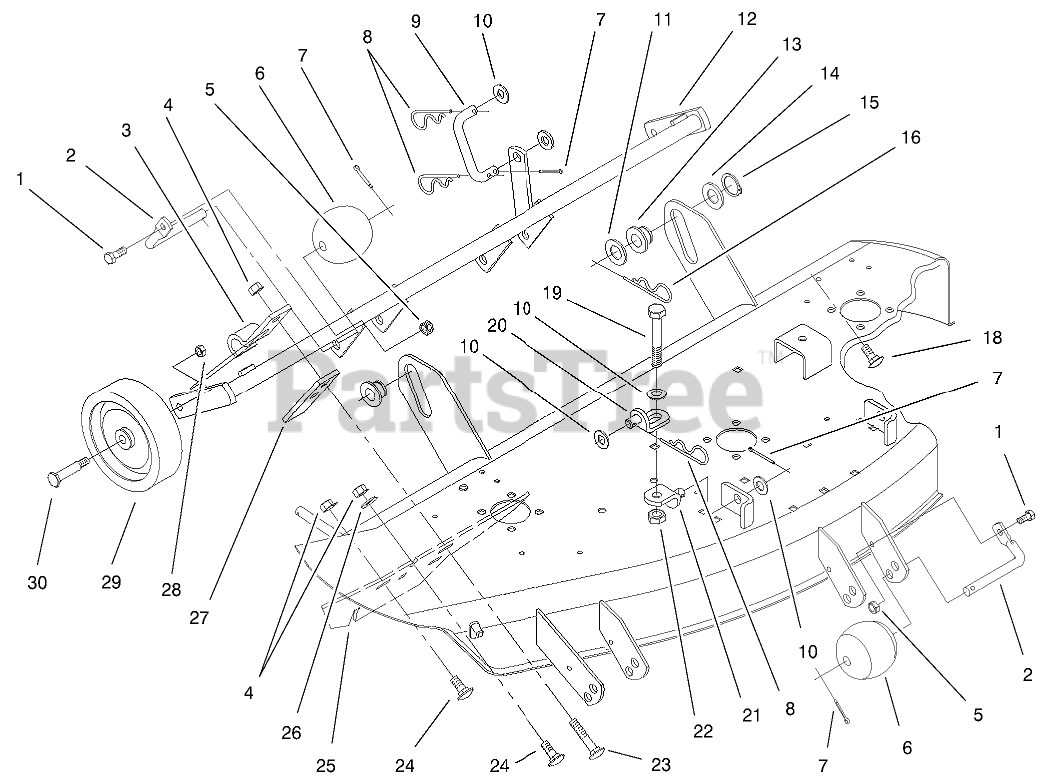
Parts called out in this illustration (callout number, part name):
1	SCREW-HH
2	Shaft-Roller
3	BRACKET-PIVOT
4	NUT-LOCK, NI
5	NUT-LOCK, NI
6	ROLLER
7	PIN-COTTER
8	PIN-COTTER, HAIR
9	LINK-REAR
10	WASHER-FLAT
11	WASHER-FLAT
12	SUPPORT-GAGE WHEEL
13	ROLLER-LIFT
14	WASHER
15	RING-RETAINING
16	PIN-HAIR
18	SCREW-CARR
19	SCREW-HH
20	BRACKET-LIFT, LOWER
21	BRACKET-LIFT, UPPER
22	NUT-JAM
23	SCREW-CARR
24	SCREW-CARR
25	PLATE-WEAR RH
26	WASHER-FLAT
28	NUT-HEX
29	WHEEL
30	BOLT-SHOULDER
